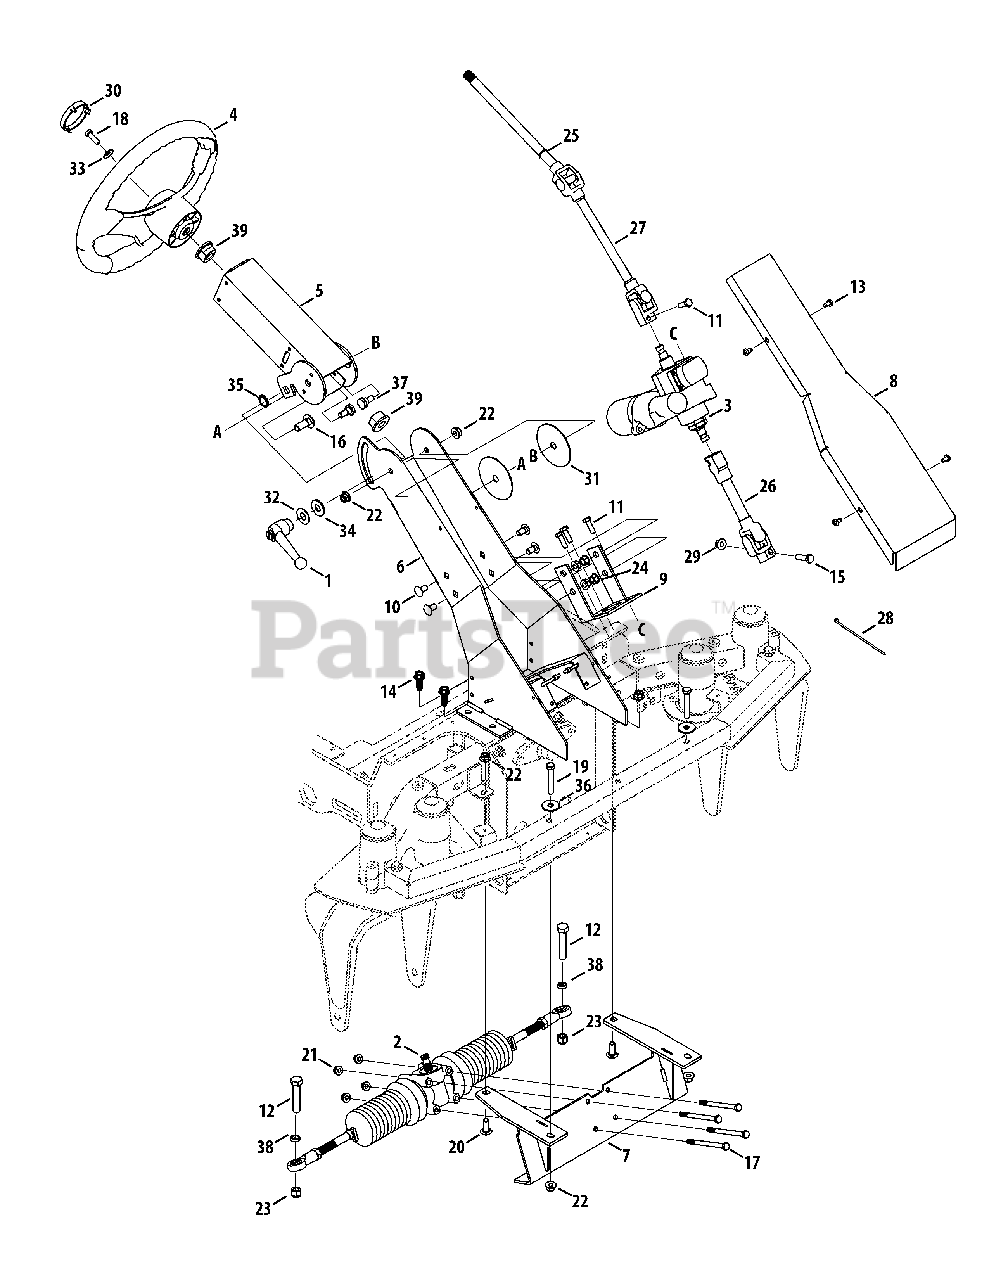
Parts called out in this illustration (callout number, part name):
1	Steering Column Adjustment Lever
2	Steering Gearbox
3	Power Steering Arm
4	Steering Wheel
5	Upper Column
6	Base Column
7	Steering Rack Mount
8	Front Column Cover
9	Power Steering Mount
10	Carriage Bolt, 3/8-16 x .750
11	Hex Cap Screw, M8-1.25 x 25.0
12	Hex Cap Screw, 1/2-20 x 2.25
13	Screw, 1/4-20 x .500
14	Screw, 3/8-16 x 1.00
15	Hex Cap Screw, 3/8-16 x 1.50
16	Carriage Bolt, 1/2-13 x 1.25
17	Hex Cap Screw, 5/16-18 x 4.00
18	Hex Cap Screw, 5/16-18 x 1.00
19	Hex Cap Screw, 3/8-16 x 2.50
20	Carriage Bolt, 3/8-16 x 1.00
21	Nut, 5/16-18, Flangelock
22	Nut, 3/8-16, Flnagelock
23	Nut, 1/2-20, Hexlock
24	Nut, 3/8-16, Flangelock
25	Retainer Ring, .625
26	Steering Shaft, Bottom
27	Steering Shaft, Top
28	Cable Tie
29	Nut, Hex Lock, 3/8-16
30	Cap, No Sprig
31	Column Wear Plate
32	Washer, .531 x 1.25 x .100
33	Bevel Washer, .340 x .872 x .060
34	Washer, .640 x 1.25 x .050
35	Lock Washer, 17 x 23.8 x 1.95
36	Washer, .406 x 1.00 x .105
37	Shoulder Bolt, .496 x .336, 3/8-16
38	Spacer, .515 x .75 x .220
39	Flange Bearing, .63 x 1.15
